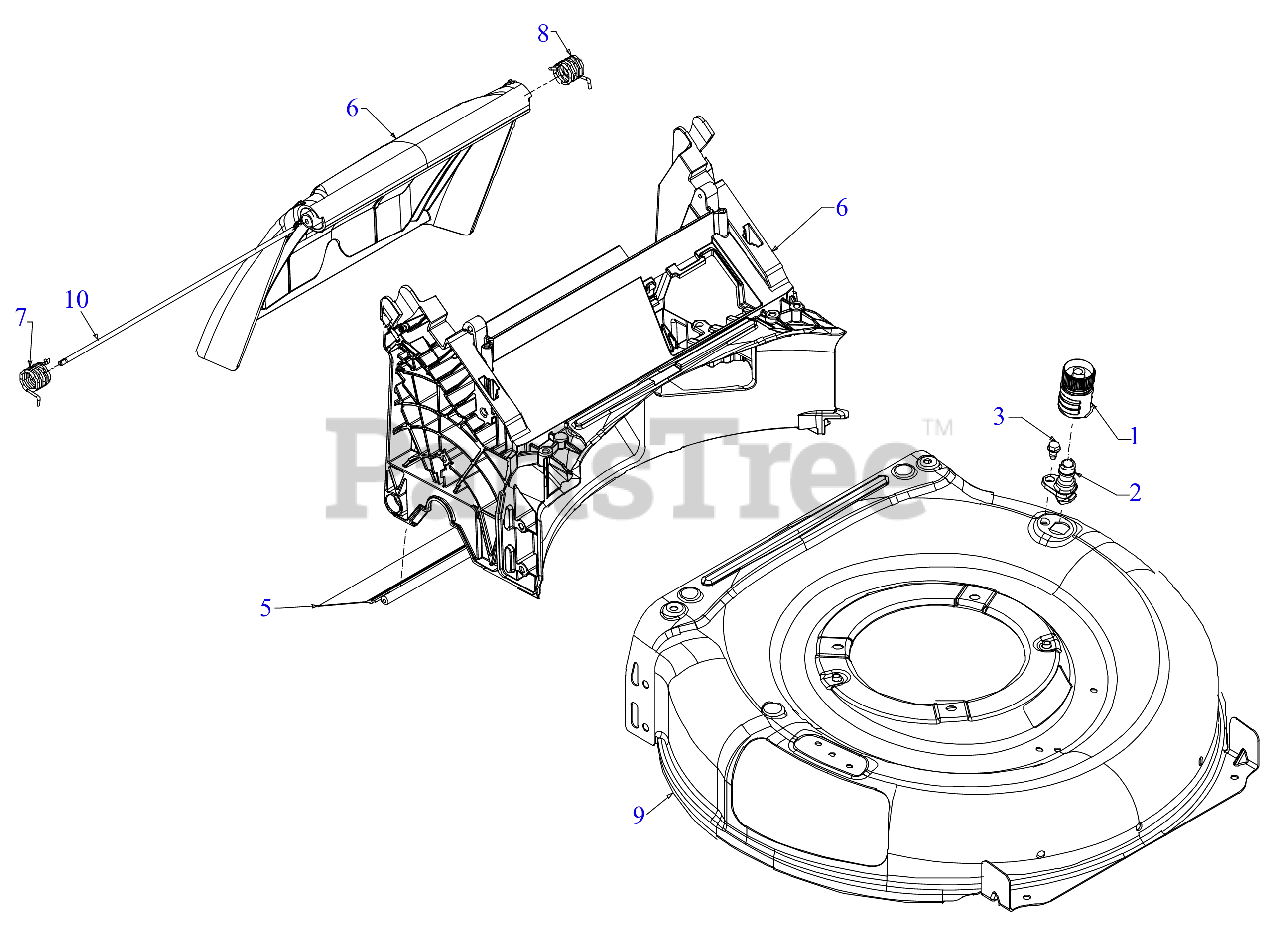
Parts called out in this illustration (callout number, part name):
1	WATER NOZZLE ADAPTER
2	DECK WASH NOZZLE
3	SHOULDER SCREW 1/4-20 x .50
5	TRAILSHIELD
6	REAR BAFFLE ASSEMBLY
7	TORSION SPRING (RH)
8	TORSION SPRING (LH)
10	REAR DOOR PIVOT ROD
